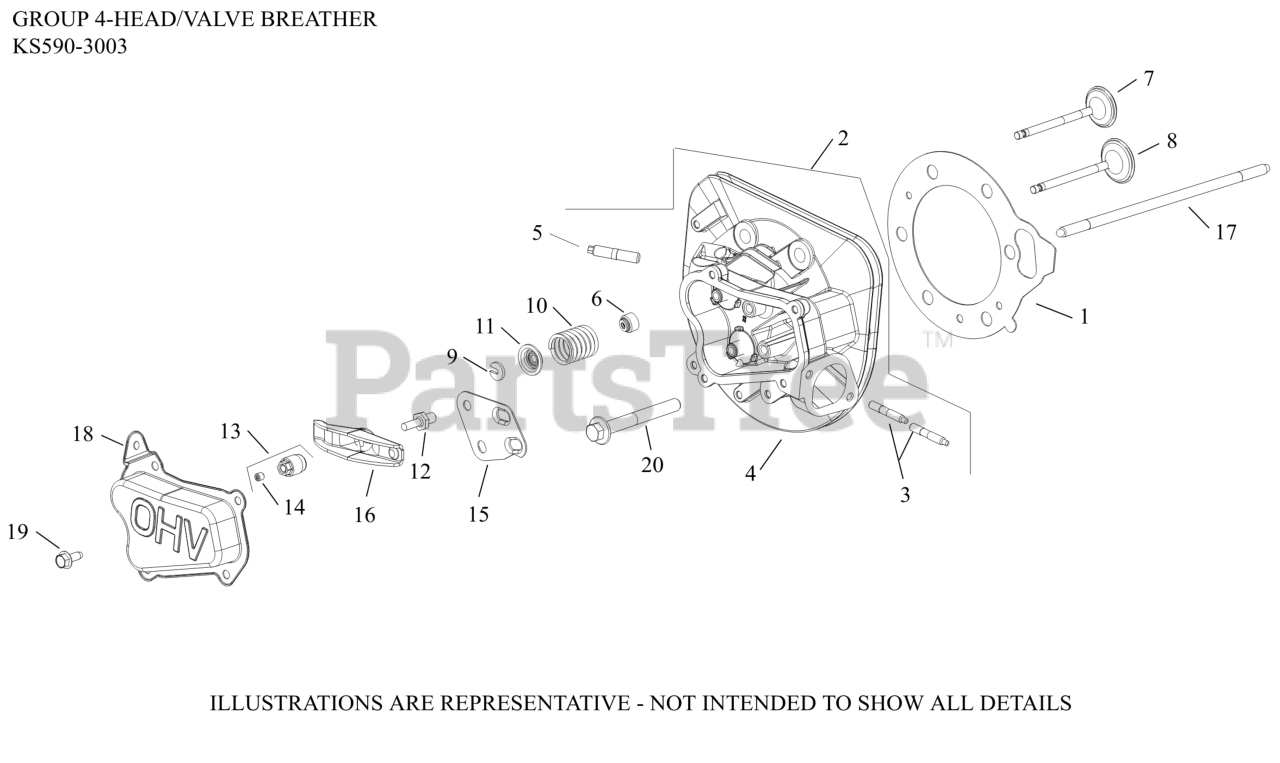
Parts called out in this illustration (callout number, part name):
1	GASKET, CYLINDER HEAD
2	HEAD ASSY (STUD INSTALLATION)
3	STUD, INTAKE MANIFOLD
4	HEAD, CLYLINDER-USE 22 318 03-S
5	STUD, EXHAUST-USE 25 072 36-S
6	SEAL, VALVE STEM
7	VALVE, EXHAUST
8	VALVE, INTAKE
9	LOCK, RETAINER
10	SPRING, VALVE
11	CAP, VALVE SPRING
12	STUD, ROCKER
13	PIVOT, ROCKER ARM-USE 20 599 04-S
13	ROCKER PIVOT ASSY
14	SCREW, SET
15	PLATE, PUSHROD GUIDE
16	ARM, ROCKER
17	ROD, PUSH
18	COVER, VALVE
19	SCREW, THREAD FORMING
20	SCREW, HEX FLANGE
